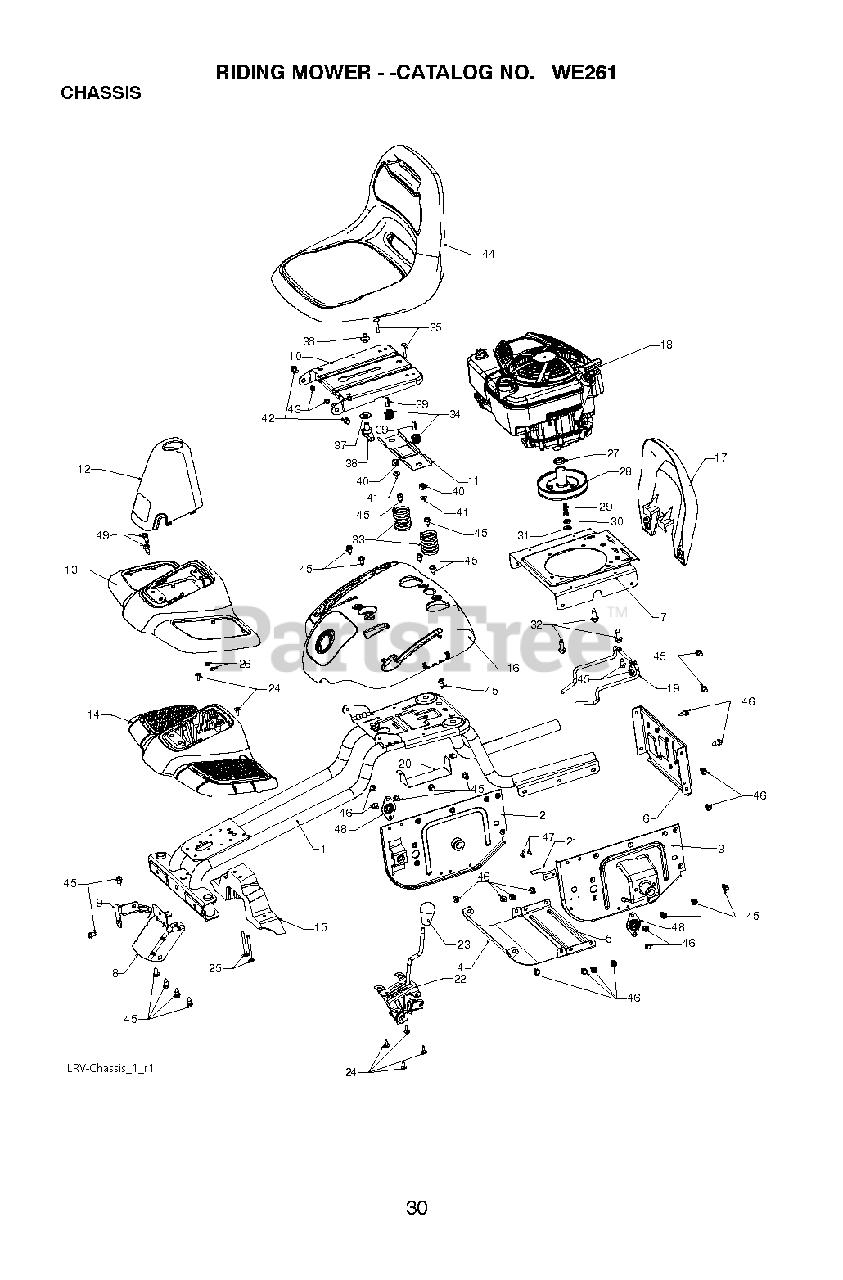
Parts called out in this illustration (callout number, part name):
1	CHASSIS.WLD.26".LRV
2	SUPPORT, AXEL LH
3	RP SUPPORT, AXLE RH
4	SHIELD, TRANSAXLE FRONT
5	STRAP.CROSS.FRICTION.DRIVE
6	COVER, FRICTION DRIVE
7	PLATE, ENGINE
8	BRACKET, CHASSIS FRONT
9	BRACKET, STEERING SUPPORT
10	PAN.ASM.SEAT.1SLOT
11	BRKT.MNTNG.SWITCH.SEAT.BLACK
12	BOOT, DUST LRV (2 2)
13	FOOTREST.AESTHETIC.WE.GRN.LRV
14	STRUCTURE, FOOT REST
15	SUPPORT, FOOT REST
16	FENDER.CNTRL.PNL.WE.GRN.LRV
17	GUARD.ENGINE.LRV
19	KEEPER, BELT
20	BRACKET, BATTERY LRV
21	LEVER, SWITCH
22	CABLE.ASM.CLUTCH.W/BRACKET
23	KNOB.OVAL.CUSTOM.BLACK
24	SCREW.#10 X 0.750.BOS (2 2)
25	BOLT.CARRIAGE
26	NUT
27	SPACER.ENGINE.B&S.LRVA
28	DISC, FRICTION ASM
29	BOLT, SCKT HD 3/8-24 X 1 .25
30	BEARING.BALL.689ZZ
31	SPACER.NEUTRAL
33	SPRING COMPRESSION
35	BOLT.ROUND.HEAD.SQUARE.NECK
36	BOLT,SHOULD
38	KNOB.SEAT.ADJ.WINGNUT
39	SPACER SPLIT 28X.96
41	NUT T
42	BOLT.SHOULDER.5/16-18
43	NUT.71038.31-18.HEX.NYLOCK
45	SCREW
46	SCREW LT
48	BEARING FLANGE BALL
49	SCREW 5/16-18X1
51	BOLT.SHOULDER.5/16-18X
52	PUSH CLIP
